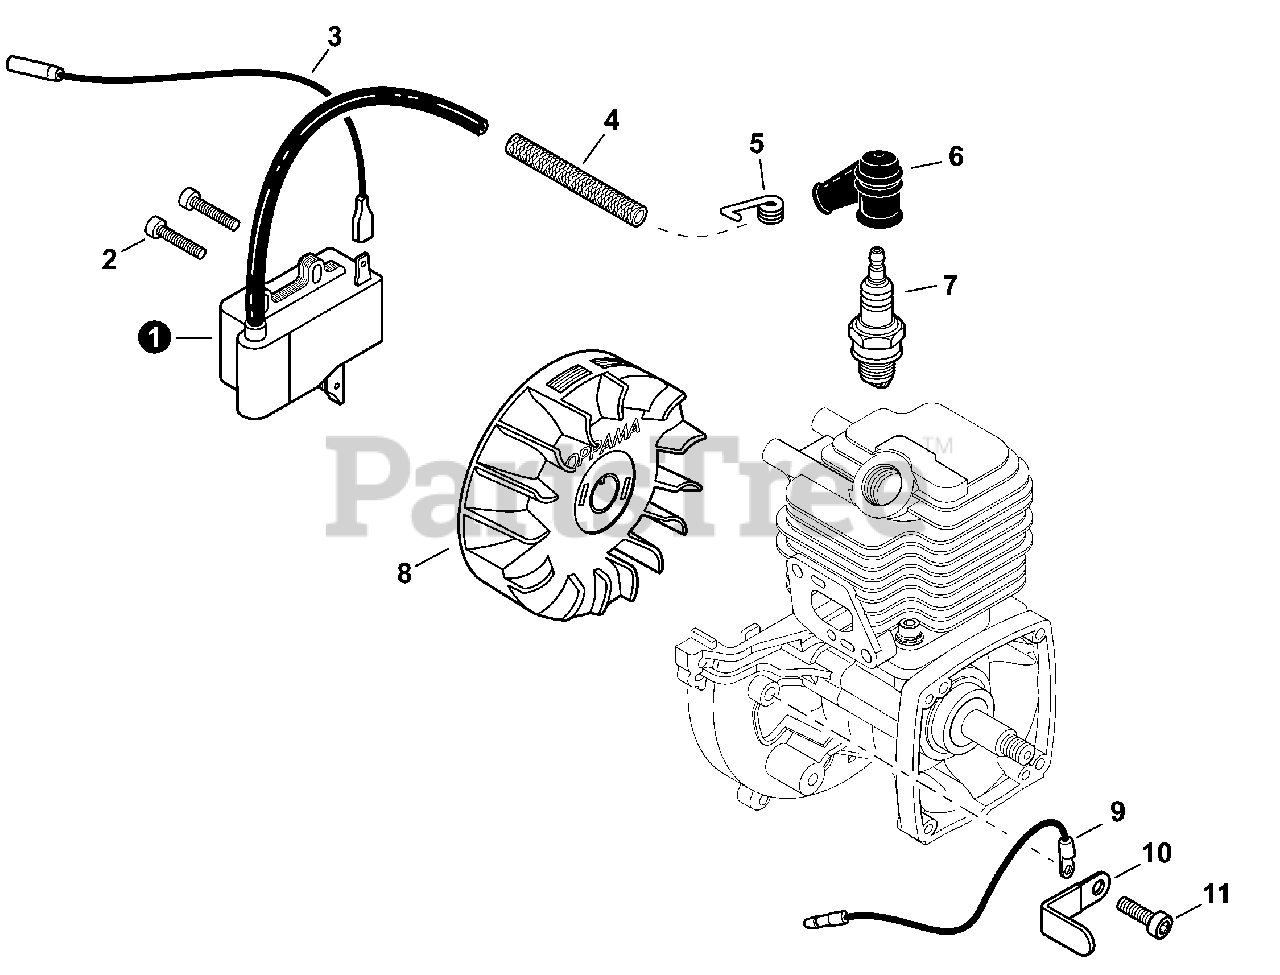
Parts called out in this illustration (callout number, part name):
1	COIL, IGNITION
2	BOLT, TORX 4×20
3	LEAD - IGNITION L= 210
4	TUBE, INSULATOR Ø8 L= 65
5	TERMINAL, SPARK PLUG
6	CAP, SPARK PLUG
7	SPARK PLUG - BPM8Y
8	FLYWHEEL
9	LEAD - GROUND L= 115
11	BOLT, TORX 5×10
